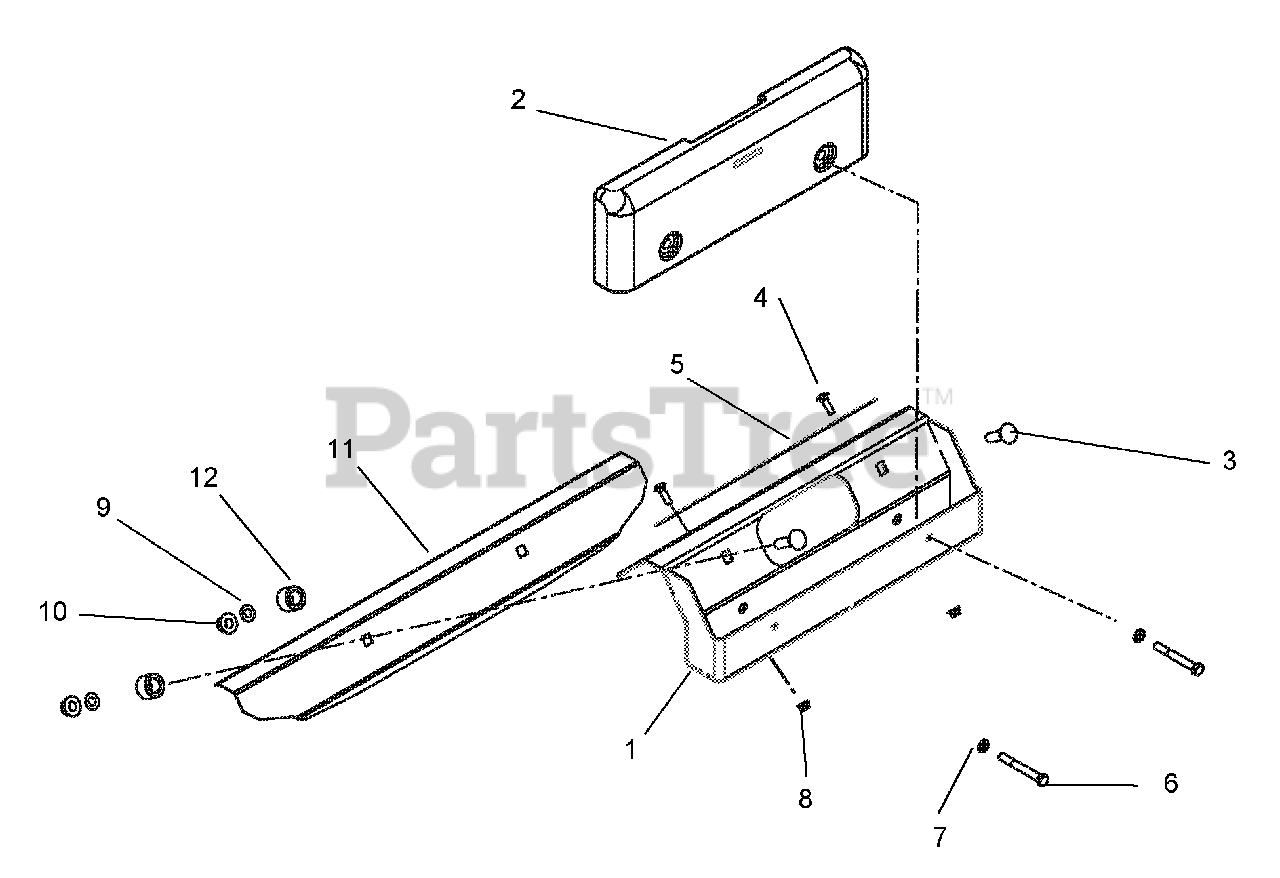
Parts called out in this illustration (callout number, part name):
1	WMT, BAGGER WEIGHT
2	WEIGHT, CAST IRON
3	BLT-RDHDSQNK .50-13X2.00GR5YZ
4	@BLT-RDHDSQNK .31-18X1.00 G5YZ
5	GRIP, ADHESIVE (1" X 16" BLK)
6	@BLT-HEX .38-16X3.00 GR5 YWZC
7	@WSHR-LK .38X.094 REG YWZC
8	@NUT-LK-NYL-FLG .31-18 YWZC
9	NUT-PUSH, .50
10	@NUT-LK-NYL-FLG .50-13 YWZC
11	FOOTREST
12	TUBE, UPPER CONTROL PIVOT
